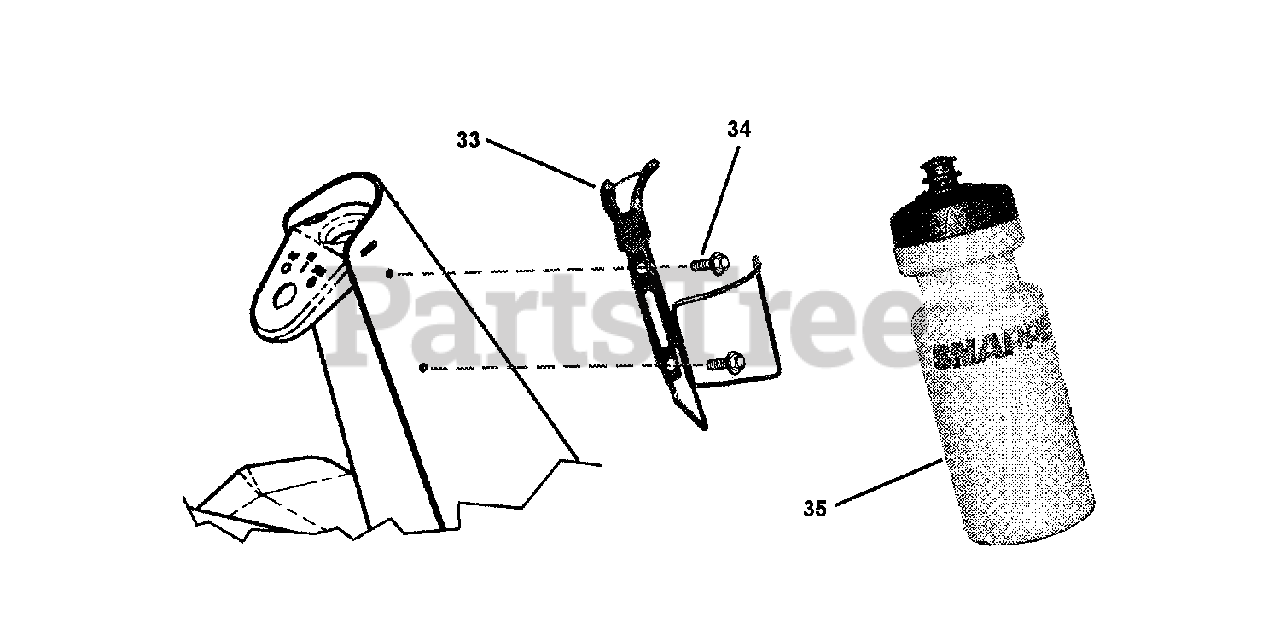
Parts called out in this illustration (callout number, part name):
33	HOLDER, Bottle (Wire)
34	SCREW, #10-24 x 1/2" Hex Washer Self-Tap (Torx)
35	BOTTLE, Water
